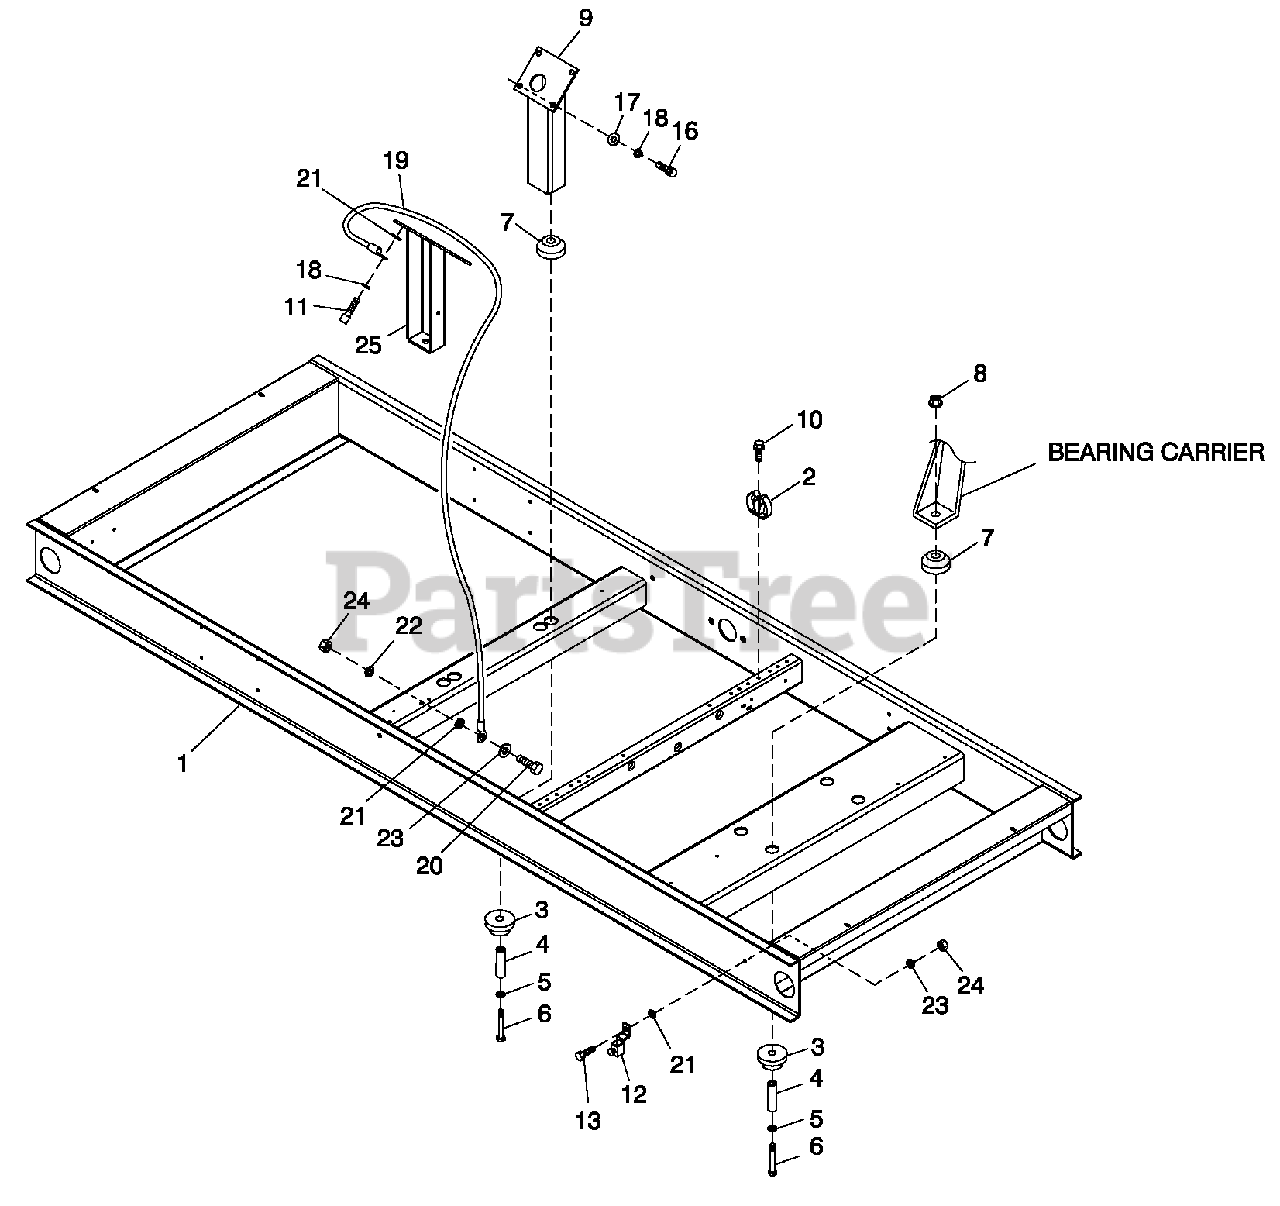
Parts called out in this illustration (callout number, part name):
1	BASE CP 6.8L70KWI5.4L 55KW DD
2	SPRING CLIP HOLDER .37-.62
3	DAMPENER VIBRATION
4	SPACER .49 X .62 X 1.87 PWDRIZINC
5	WASHER FLAT M12
6	SCREW HHC M12-1.75 X 85 G8.8
7	DAMPENER VIBRATION 50 WHITE
8	NUT LOCKING M12-1.75
9	SUPPORT ENG 5.4L LHIRH 6.8L RH
10	SCREW HHTT M4-0.7X8BP
11	S CREW SHC M10-1.5 X 60 G12.9 (6.8L)
12	LUG SOLDERLESS 3I0-#4X 13I32 CU
13	SCREW HHC M8-1.25X 25 G8.8
16	SCREW SHC M10-1.5 X 30 G 12.9
17	WASHER FLAT 3I8-M10 ZINC
18	WASHER LOCK M10
19	ASSY WIRE 14.00"
20	SCREW HHC M8-1.25X 30 G8.8
21	WASHER SHAKEPROOFINT 3I8
22	WASHER LOCK M8-5I16
23	WASHER FLAT 5I16-M8 ZINC
24	NUT HEX M8-1.25 G8YEL CHR
25	SUPPORT ENGINE LH (5.4L ONLY)
